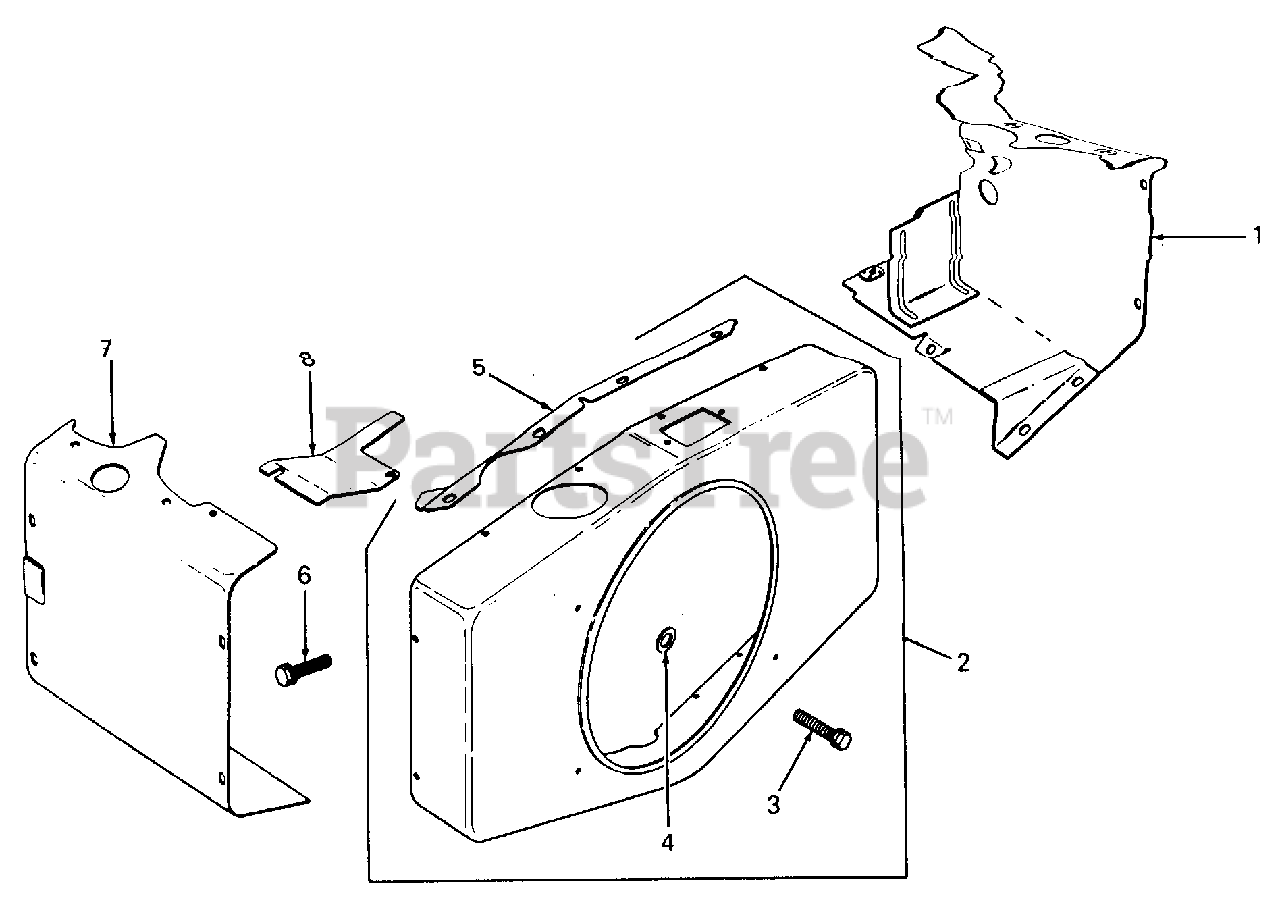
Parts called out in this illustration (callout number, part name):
1	Baffle, #1 Cylinder Head
2	Kit, Blower Housing
3	Screw, Self Tap, 1/4-20 X 5/8
4	Washer, Flat, 1/4
5	Support, Upper Housing
6	Screw, Hex Wash Hd, 1/4-20 X 7/16
7	Baffle, #2 Cylinder Head
8	Baffle, #2 Cylinder Top
